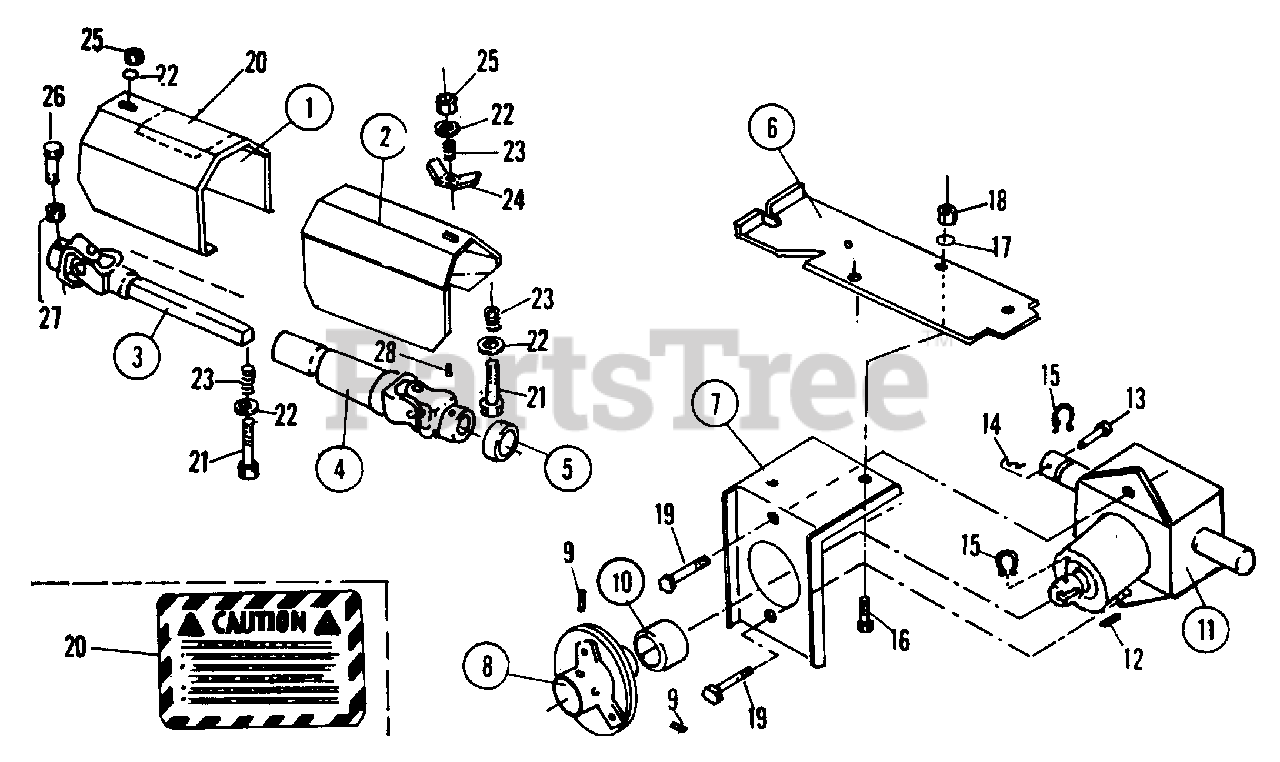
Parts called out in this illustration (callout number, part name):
1	COVER, LEFT SIDE PTO
2	COVER, RIGHT SIDE PTO
3	SLIP-JOINT, FEMALE END
4	SLIP-JOINT, MALE END
5	SPACER, SLIP-JOINT TO GEAR BOX
6	PLATE, GEAR BOX MOUNTING
7	BRACKET, GEAR BOX MOUNTING
8	COUPLER ASSEMBLY (ENGINE TO GEARBOX)
9	SETSCREW, 5/16-18 x 5/16 HEX SOCKET
10	SPACER, COUPLER TO GEARBOX
11	GEARBOX ASSEMBLY, COMPLETE (PEERLESS #3573P91)
12	KEY, GEAR BOX INPUT SHAFT
13	PIN, SHEAR
14	PIN, COTTER
15	RING, RETAINING
16	BOLT, 3/8-16 x 1" HEX HEAD
17	LOCKWASHER, 3/8"
18	NUT, 3/8-16 x HEX
19	BOLT, 1/2-13 x 3/4 HEX HEAD
20	DECAL, CAUTION
21	BOLT, 3/8-16 x 2-3/4 HEX HEAD
22	WASHER, 7/16 FLAT
23	SPRING, PTO COVER
24	WING-BRACKET
25	LOCKNUT, 3/8-16 HEX
26	BOLT, 1/4C x 2 HEX
27	LOCKNUT, 1/4C HEX
28	FITTING, GREASE
